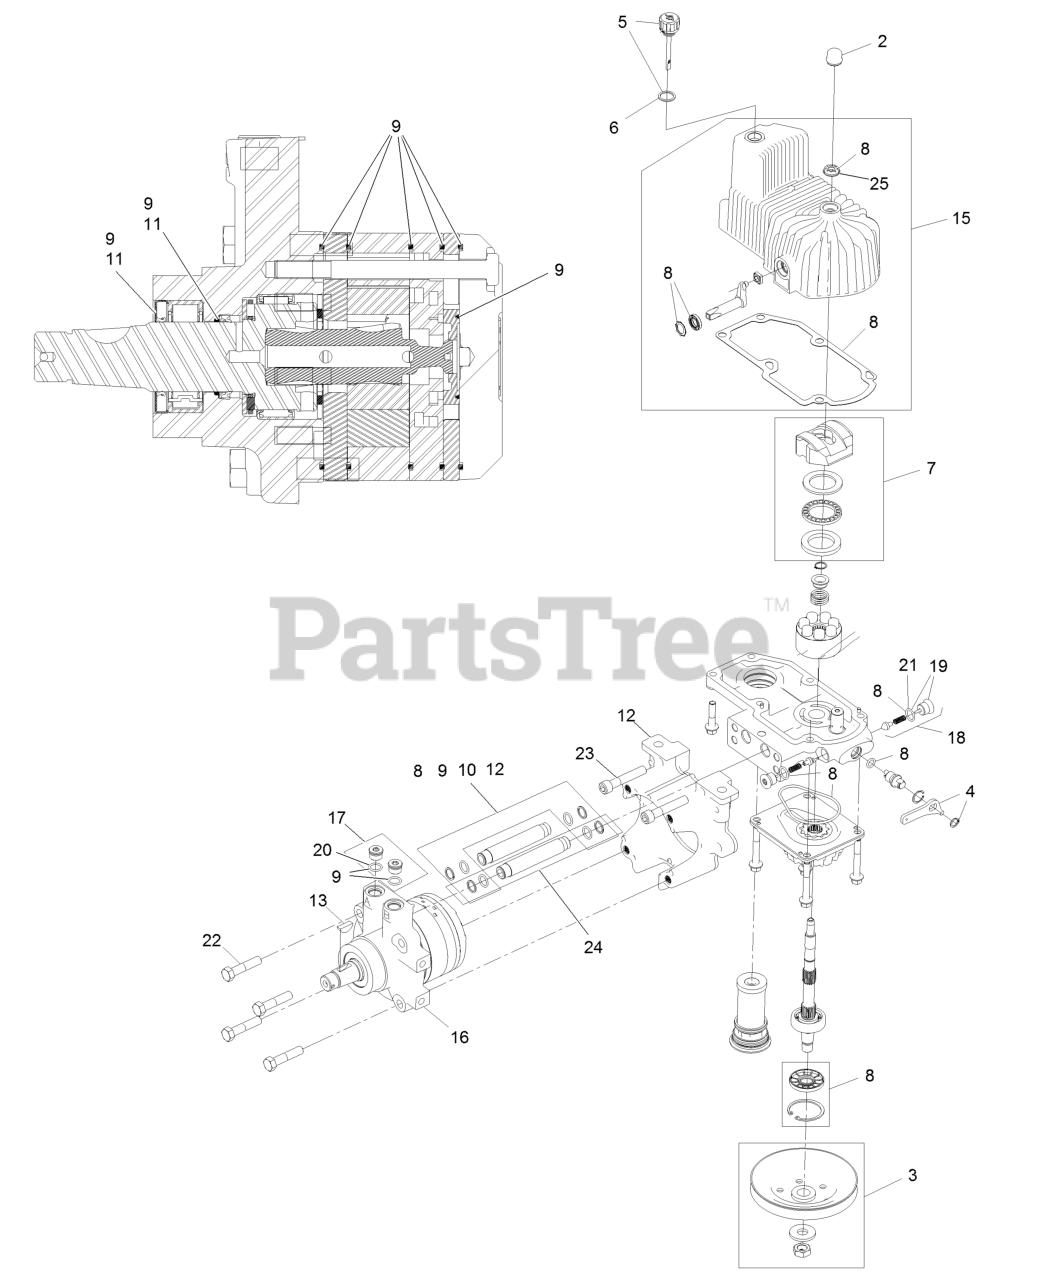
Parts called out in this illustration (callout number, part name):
2	Cover-Shaft, Hydro
3	Pulley Kit
4	Handle-Bypass Valve, Hydro
5	Dipstick-Hydro W/Gasket
6	Gasket-Dipstick, Hydro
7	Swash Block Kit
8	Pump Seal Kit
9	Motor Seal Kit
10	Tube Seal Kit
11	Output Shaft Seal Kit
12	Nose Cup-Uht
13	Key-Woodruff 5/16 X 1
15	Housing-LH
16	Motor-Hydraulic LH 240Cc
17	Magnetic Plugs Service Kit
18	Check Valve ASM
19	Plug-Check (W/O-Ring)
21	O-Ring-Check Valve
22	Screw-HH 1/2-20 X 2 1/4
23	Screw-HSH 1/2-20 X 2 3/4
24	Hydraulic Tube Kit
25	Seal-Fan Drive
99	Flow Test Kit
99	Puller-Pulley
